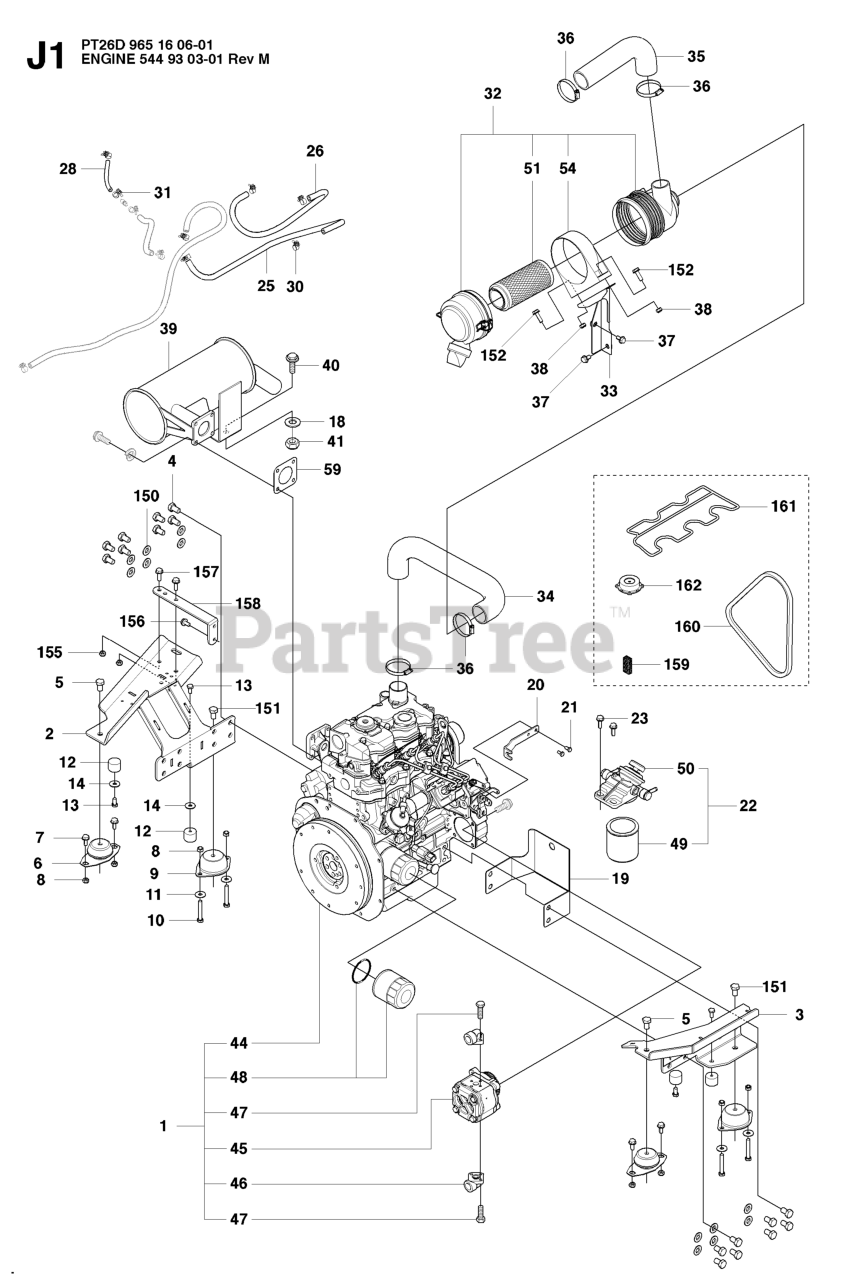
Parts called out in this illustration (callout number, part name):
6	ANTIVIBRATION ELEMENT ENGINE
8	LOCKNUT M8
9	ANTIVIBRATION ELEMENT ENGINE
11	WASHER BRB 8.4X17
12	ANTIVIBRATION ELEMENT
20	BRACKET THROTTLE WIRE
23	BOLT
30	RP HOSE CLAMP FUEL HOSE
32	AIR CLEANER
34	HOSE AIR INTAKE
35	HOSE AIR INTAKE PT 26D 2006-20
38	LOCKNUT M8
39	CATALYTIC CONVERTER
41	LOCKNUT M8
45	HYDRAULIC PUMP
46	CONNECTION
47	SCREW M6S 6X20
49	FUEL FILTER
50	FILTER HOLDER WITH PRIMING PU
51	AIR FILTER
54	BRACKET AIR CLEANER
151	Screw M10x25
152	BOLT
155	LOCKNUT M8
157	BOLT
